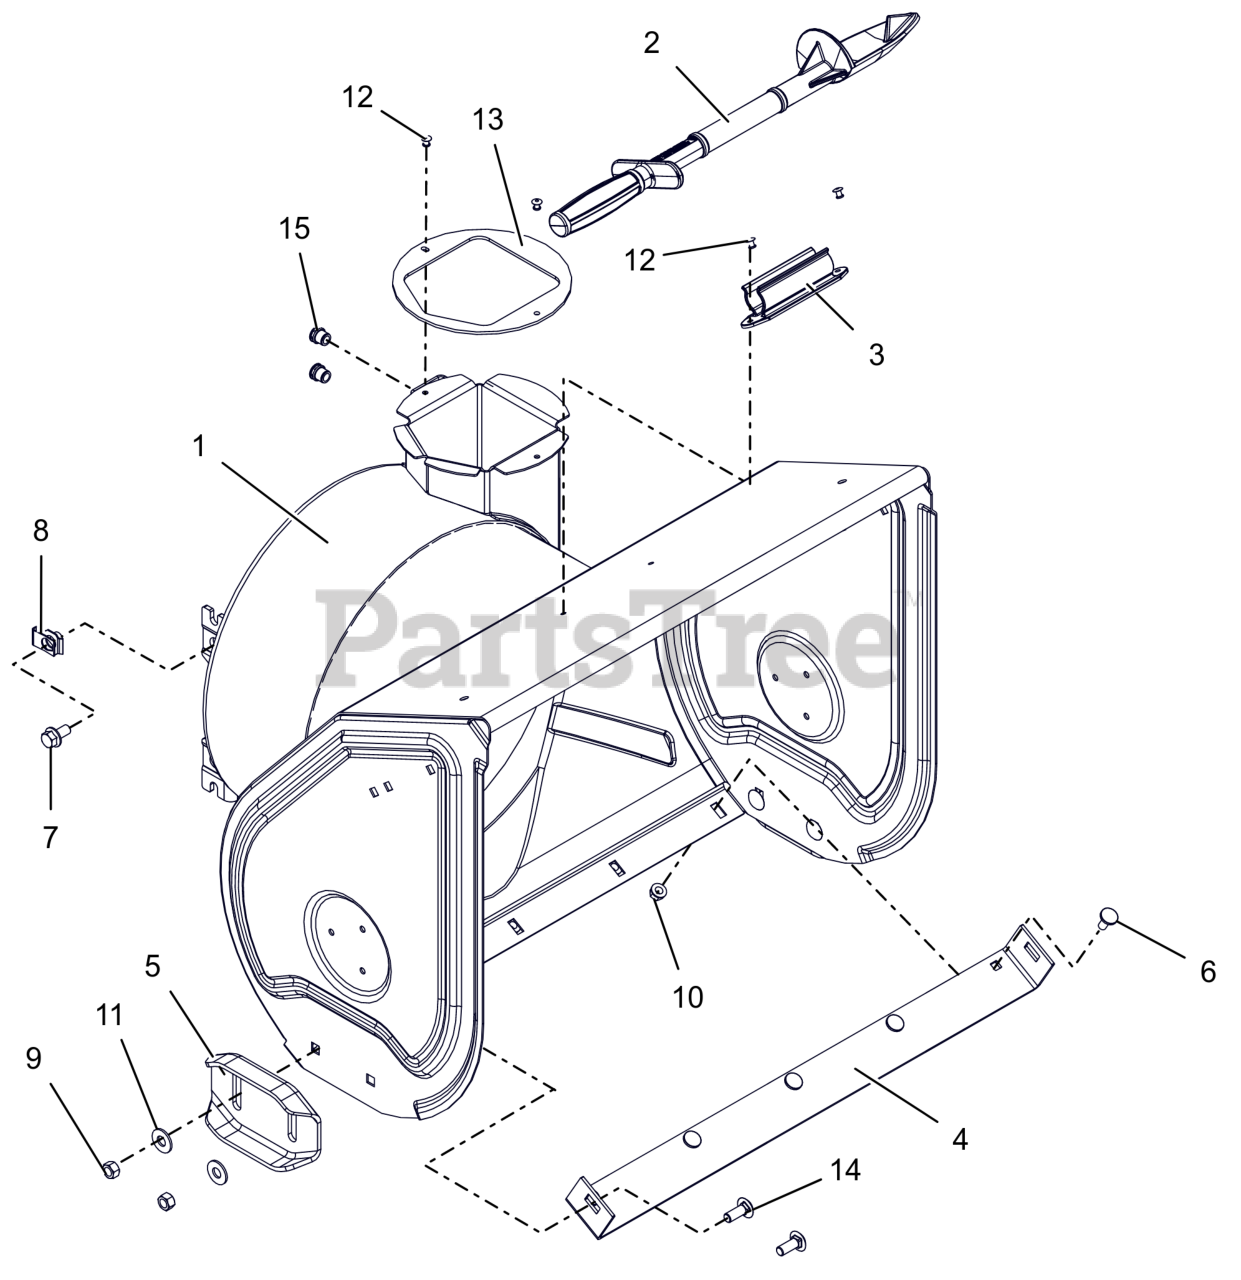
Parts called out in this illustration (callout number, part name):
1	BLOWER HOUSING W/DECAL 24"
2	DEVICE, SNOW CLEAN OUT
3	MOUNT, SNOW CLEAN OUT
4	BLADE, SCRAPER-24"
5	SKID SHOE, REVERSIBLE - ORANGE
6	BOLT, MODIFIED HEAD CARRIAGE
8	NUT-RTNR .375-16X.37
9	NUT-LK-CTR .38-16 ZC120
10	NUT-LK-TOP-FLG .312-18 GF ZCC
11	WSHR,FLT .438X1.00X.083 ZCC
12	RVT, POP .1875 ZCC
13	BAFFLE, DISCHARGE NECK
14	BLT,RHSSN .38-16X1.00 G5 ZCC
15	NUT,THD,INSERT .38-16 ZC120
